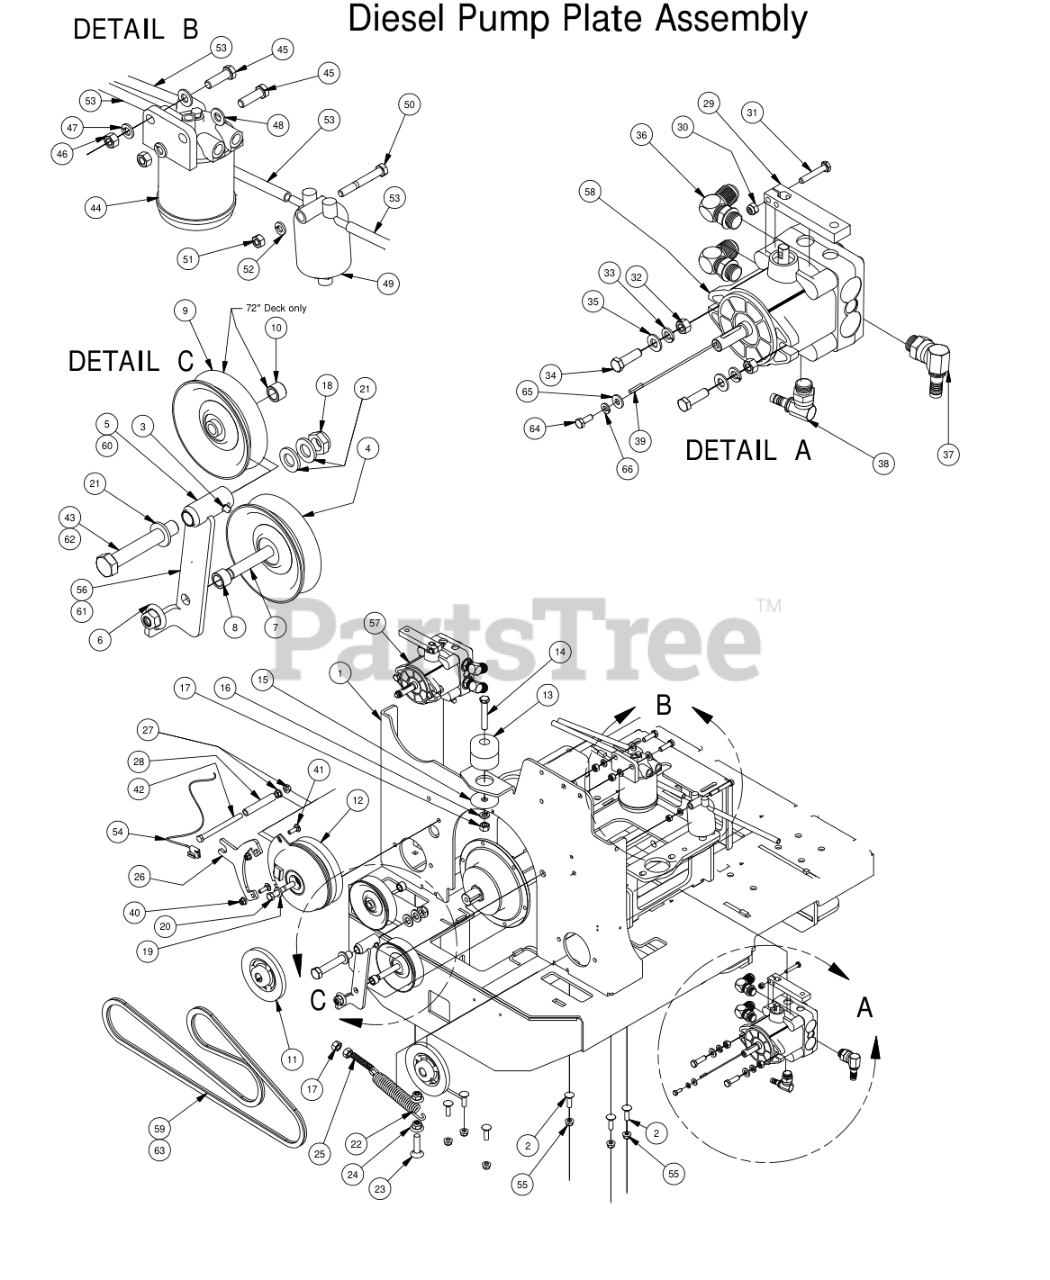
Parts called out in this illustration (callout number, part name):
1	Pump Plate Diesel
2	3/8" x 1 1/4" Carriage Bolt
3	1/4" Drive in Grease Fitting
4	4 3/4" Idler Pulley
5	Pump Idler Bracket only for 61" Deck
6	1/2-13 Nylon Flange Nut-Orange
7	1/2" x 3" Hex Bolt
8	1/2 x 1/2 Spacer
9	5" Idler Pulley only for 72" Deck Diesel
10	5/8" x 1/" Collar Spacer only for 72" Deck Diesel
11	5" Pump Pulley
12	Clutch Assembly for Diesel
13	Armor Plated Mount-Rear Mount
14	1/2" x 3" Hex Bolt
15	Snubbing Washer
16	1/2" Lock Washer
17	1/2" Hex Nut
18	5/8" Nylock (1/2 Jam)
19	7/16" Lock Washer
20	7/16" x 2 3/4" Fine Thread Bolt
21	.630 ID x 1.122 OD x .142 THK Plastic Washer
22	Deck Idler Spring
23	1/2 x 2" Carriage Bolt
24	1/2-13 Nylon Flange Nut-Orange
25	1/2-13 x 2-1/2 All Thd Stud
26	Diesel PTO Engager Holder
27	3/8" Flange Nut
28	3/8 hose 4" long
30	1/4" Nylock Nut
31	1/4" x 1 1/2" Bolt
32	3/8" Hex Nut
33	3/8" Lock Washer
34	3/8" x 1 1/2" Hex Bolt
35	3/8" Flat Washer
36	90 Degree Adaptor 6801-L-8-8 Fitting
37	90 Degree Fitting 1/2" x 3/4" 4601-8-8
38	90 Degree Fitting 3/8" X 9/16"- 4601-6-6
39	5mm x 1.25" Key
40	5/16" Flange Nut
41	5/16" x 1" Carriage Bolt
42	3/8-16 x 5 Hex Bolt - Grade 5
43	5/8" x 4" Hex Bolt 61" Deck only
44	Fuel Filter
45	3/8" x 1 1/4" Hex Bolt
46	3/8" Hex Nut
47	3/8" Lock Washer
48	3/8" Flat Washer
49	Caterpillar Fuel Bowl Kit
50	5/16" x 2 1/2" Bolt
52	5/16" Lock Washer
53	5/16" fuel line hose
54	Clutch Pigtail
55	3/8" Nylock Flange Nut
56	Pump Idler Assembly Components 3,4,5,6,7,8, only for 61" Deck
57	Left Pump 16cc - AOS Diesel 35Hp Diesel
58	Right Pump 16cc - AOS Diesel 35Hp Diesel
59	Pump Belt for 72" Deck
60	Diesel Pump Idler only on 72" Deck
61	Diesel Pump Idler Assembly Components 3,4,5,6,7,8,9,10 only for 72" Deck
62	5/8 x 5 1/2 Bolt only for 72" Deck
63	Pump Belt for 61" Deck
64	M6-1.0 X 16MM Hex Bolt
65	1/4" Flat Washer
66	1/4" Lock Washer
